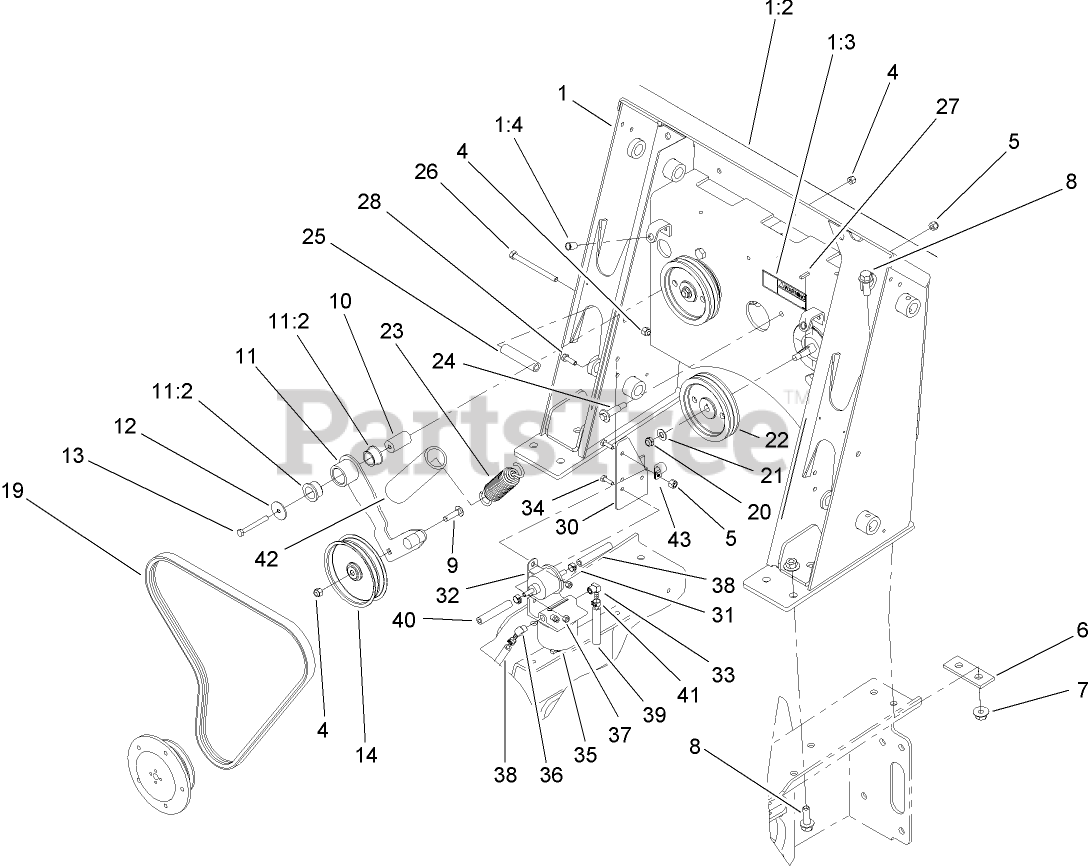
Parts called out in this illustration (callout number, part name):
1	LOADER TOWER ASM
1:2	DECAL-PANEL, CONTROL
1:3	DECAL-DANGER
1:4	INSERT-THREADED
4	NUT-LOCK, NI
5	NUT-LOCK, NI
6	PLATE-STIFFENER
7	NUT-LOCK, FLANGE
8	SCREW-HHF
9	SCREW-CARR
10	SPACER-MOUNTING
11	IDLER ARM ASM
11:2	BUSHING-FLANGE
12	WASHER-FLAT
13	SCREW-HH
14	PULLEY-IDLER
19	V-BELT
20	NUT-LOCK, NI
21	WASHER-FLAT
22	PULLEY
23	SPRING-EXTENSION
24	BOLT-WHEEL
25	TUBE-SPACER
26	SCREW-HH
28	SCREW-HH
30	BRACKET-PUMP, FUEL
31	CLAMP-HOSE
32	PUMP-FUEL, ELECTRIC
33	ELBOW
34	SCREW-HH
35	SEPARATOR-FILTER / WATER
36	FITTING-ELBOW
37	NUT-LOCK, NI
38	HOSE-LP
39	HOSE-FUEL
40	HOSE-FUEL
41	CLAMP-HOSE
42	RETAINER-SPRING
43	CLAMP-R
